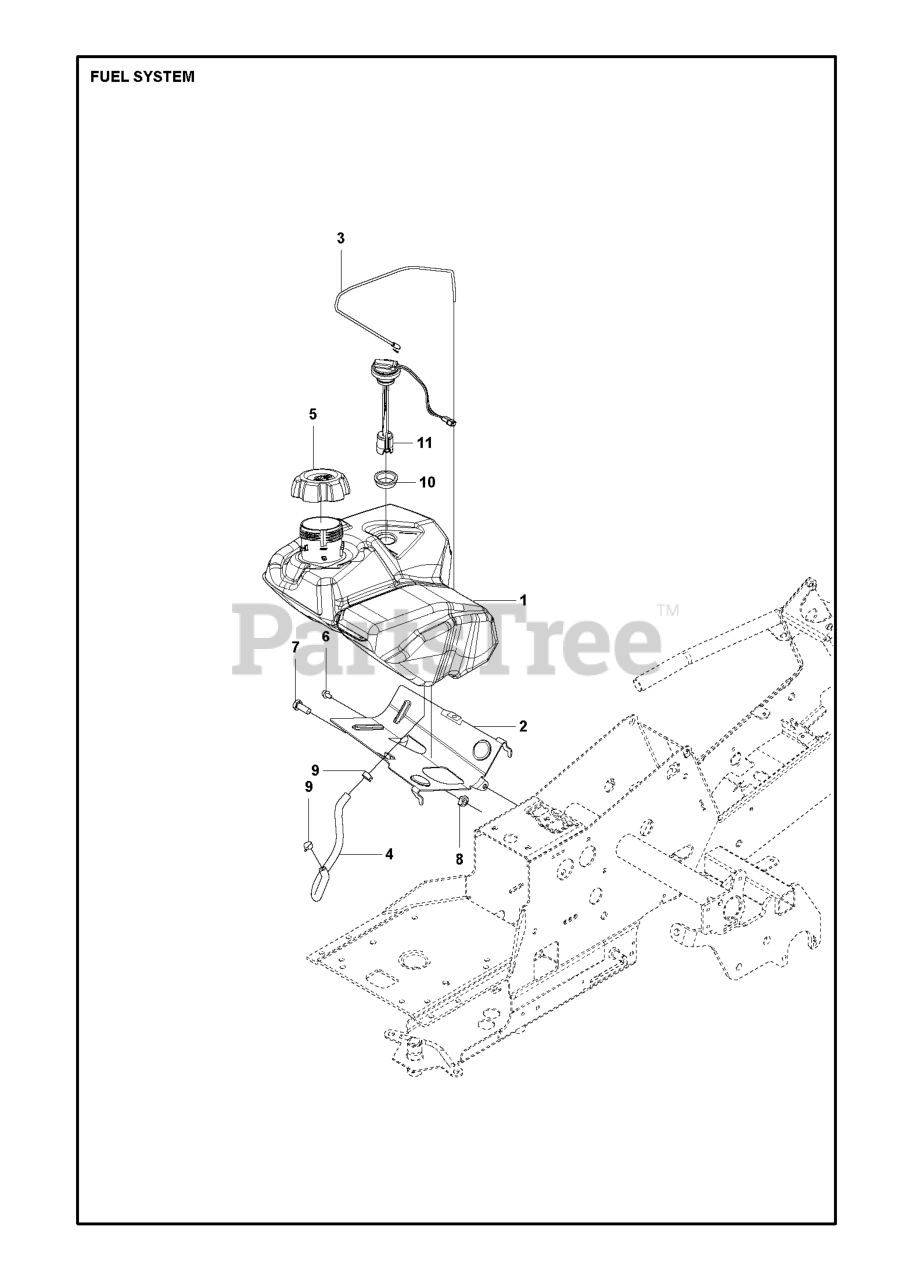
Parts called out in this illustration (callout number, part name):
5	CAP.ASSY.FUEL.3".N-EPA.GRY.498
7	Screw M10x25
8	LOCKNUT M6
